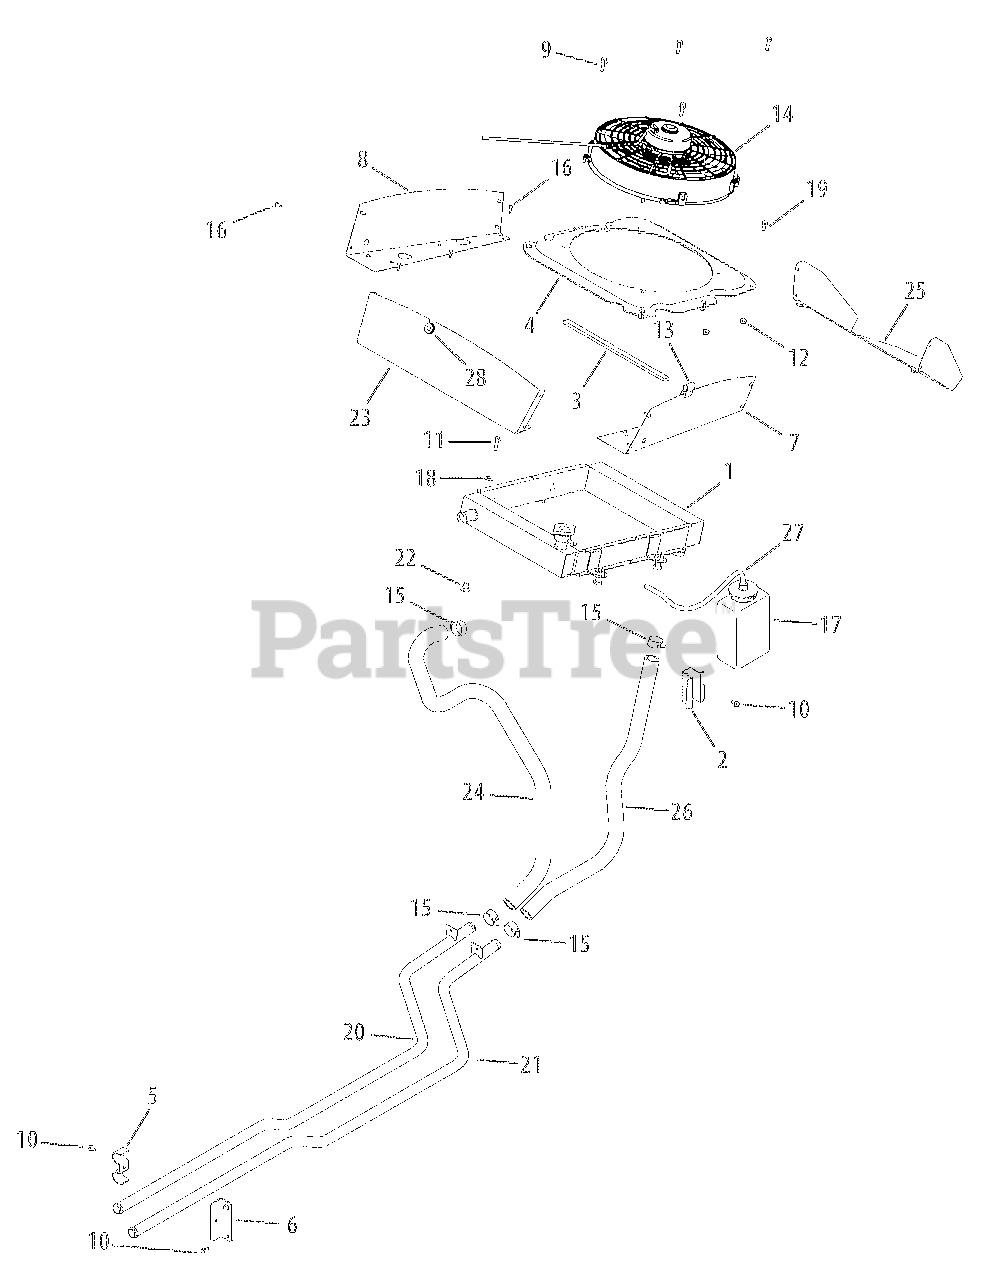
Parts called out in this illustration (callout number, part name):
1	Radiator Asm, zin Core
2	Brkt, over Flow, bottle
3	Tape, .625 Wide x .25 Thk Foam
4	Shrd, Fan, Mount
5	Brkt, tube, uv
6	Brkt, rdtr Hose
9	Hhcs, 1/4-20, 1.00, gr5
10	Scr, tt, 1/4-20, 0.500, hxindwsh
11	Scr, tt, 1/4-20, 1.000, hxindwsh
12	Nut, flglk, 1/4-20, grf, nylon
13	Heat Baffle Seal
14	Fan, electric, 12v, w/Guard
15	Clamp, hose, adj
16	Pop Rivet 3/16 Dia x .450, sty1
17	Cntnr, over Flow, coolant
18	Wash, flat, .28 x .74 x .063
19	Scr., 1/4-20 x .620
20	Tube, inside, rdtr 4x4
21	Tube, outside, rdtr 4x4
22	Spcr, Step
24	Hose, rdtr, frt 4x4
26	Hose, rdtr, frt 4x4
27	Tube, overflow, rdtr
28	Grommet, Rubber, Yan
